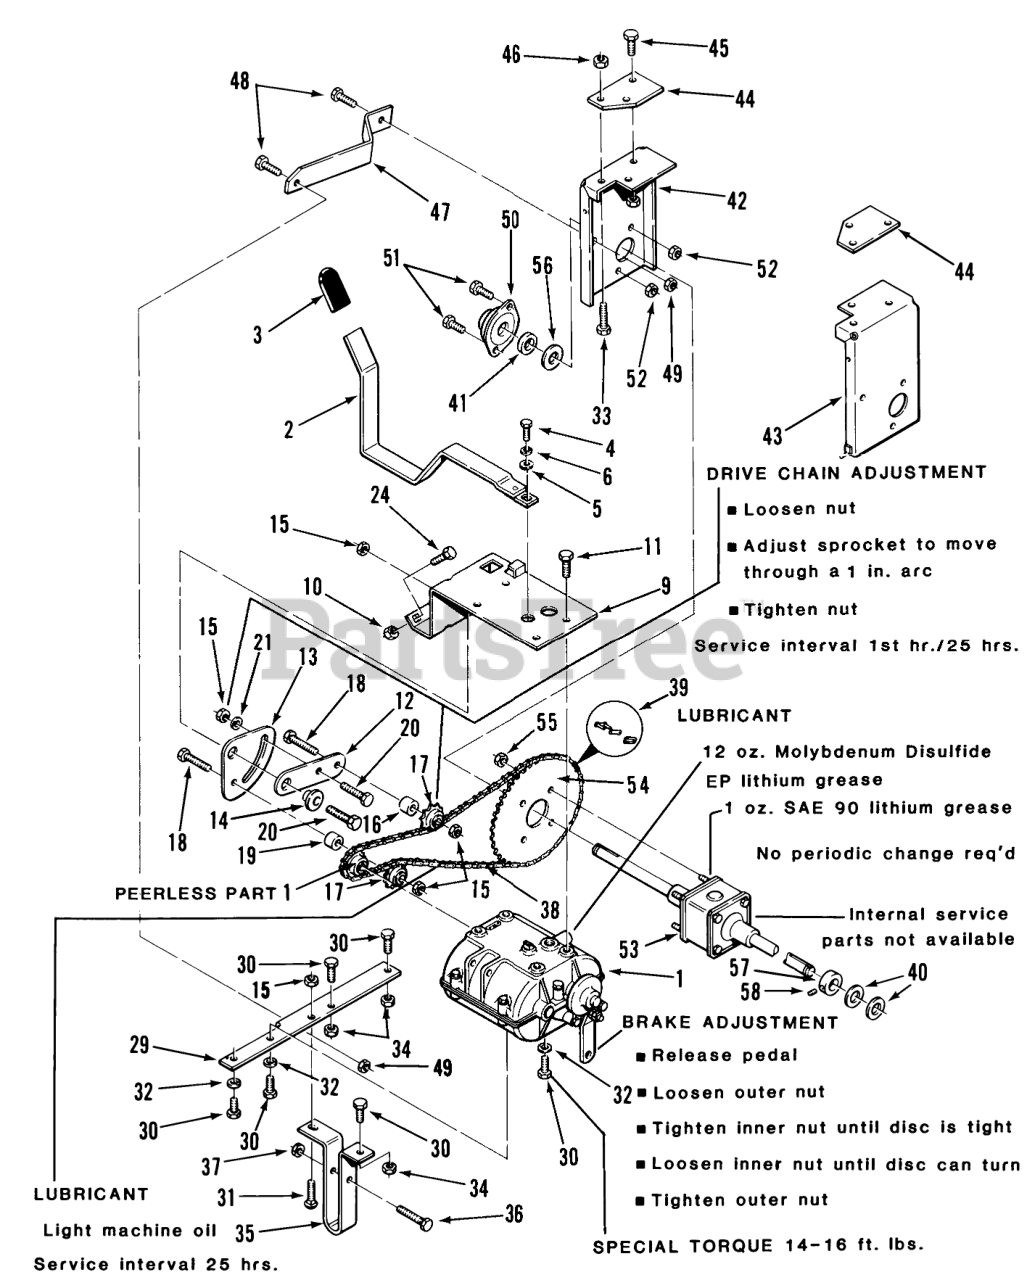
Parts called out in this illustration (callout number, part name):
1	Transmission-Peerless Mod 724A
2	Shift Lever
4	Bolt 1/4-28 X 7/8
5	WASHER
6	Washer
9	Idler Support
10	Nut
11	Screw
12	Plate-Upper Idler
13	Plate-Lower Idler
14	SPACER-BUSHING
15	Nut
16	SPACER-SPROCKET
17	IDLER-SPROCKET
18	Bolt
19	SPACER
20	BOLT HEX SPECIAL
21	Washer
24	Bolt
29	Washer-Thrust
30	Bolt
31	Bolt
32	Lockwasher
33	Bolt
34	Nut
35	Mower Guide
36	Bolt
37	Nut
38	CHAIN-ROLLER
39	MASTER LINK CHAIN
40	WASHER
41	Spacer
42	Rear Axle Bracket RH
43	Rear Axle Bracket LH
44	Plate Rear Axle Support
45	Bolt
46	Nut
47	Brace-Rear Axle Bracket RH
48	Bolt
49	Nut
50	BEARING-SIDE FLANGE
51	Bolt
52	Nut
53	ASSY-DIFFERENTIAL
54	SPROCKET
55	Nut
56	WASHER
57	Collar
58	SCREW-SET
